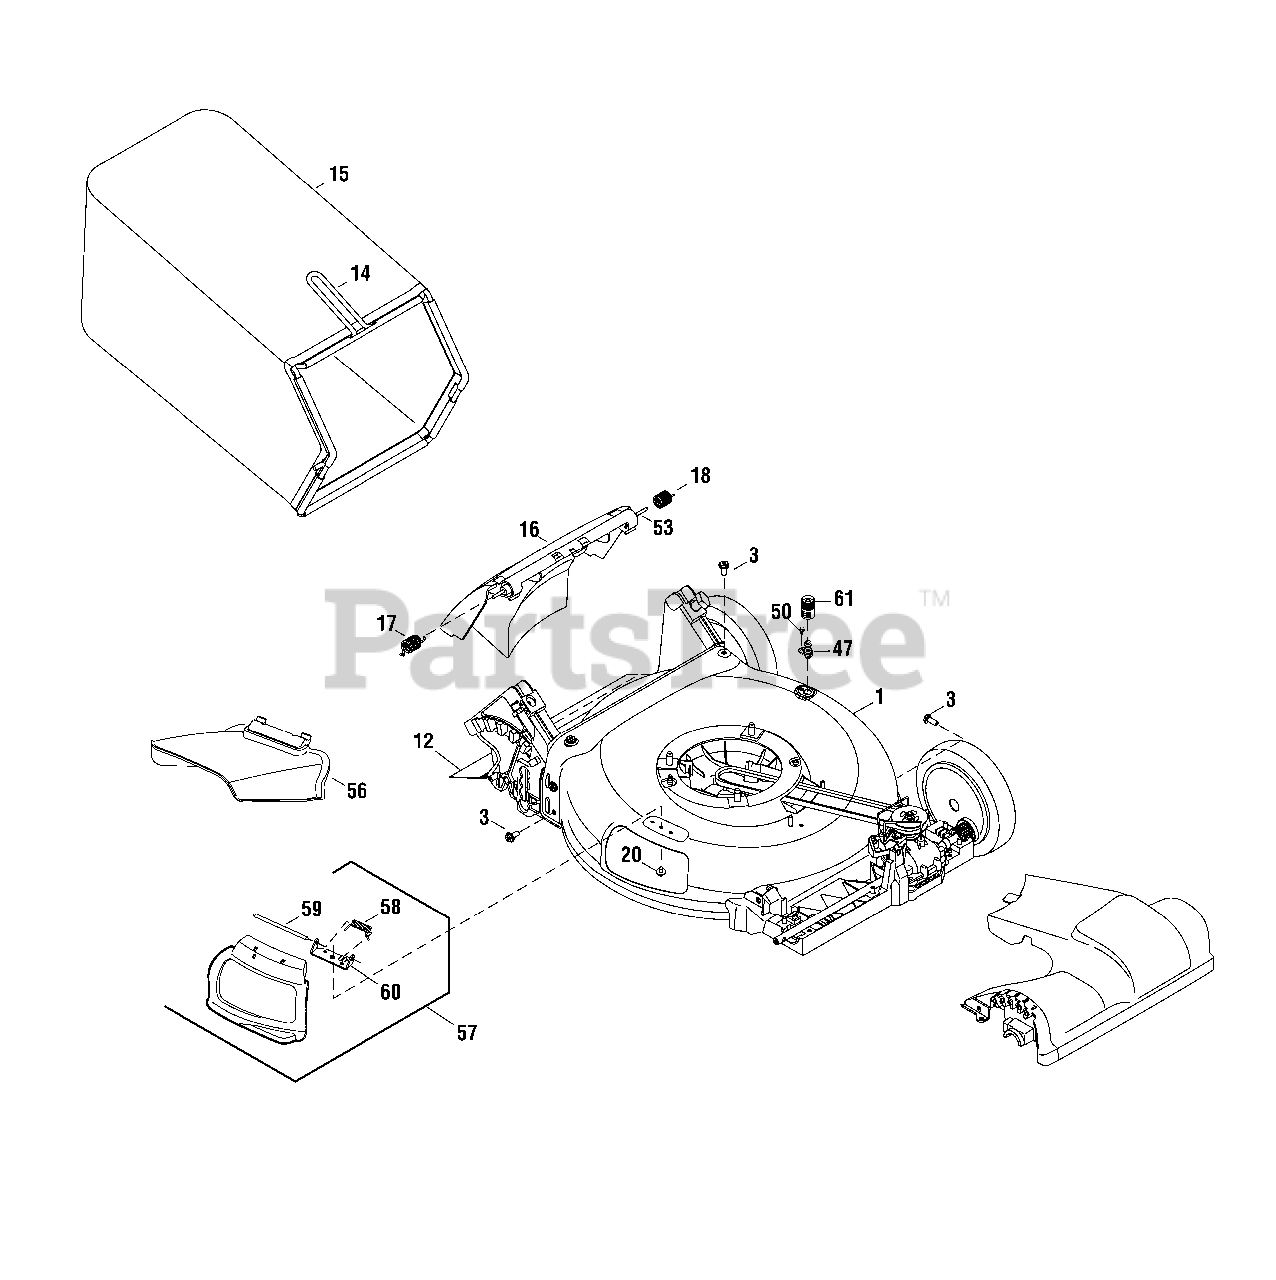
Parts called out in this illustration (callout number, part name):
3	SCREW, 5/16-14 x 3/4
12	SHIELD, Trailing
14	FRAME, Grass Bag
15	BAG, Grass
16	DOOR, Rear Discharge
17	SPRING, Torsion, RH
18	SPRING, Torsion, LH
47	ROD, Pivot
50	BOLT, Shoulder, 1/4-20 x 1/2
53	CHUTE, Side Discharge
54	ADAPTER, Water Nozzle
55	NOZZLE, Water
56	SCREW, 1/4-20 x 1/2
57	MULCH PLUG
58	PIN, Hinge
59	BRACKET, Chute Deflector
60	SPRING, Torsion
